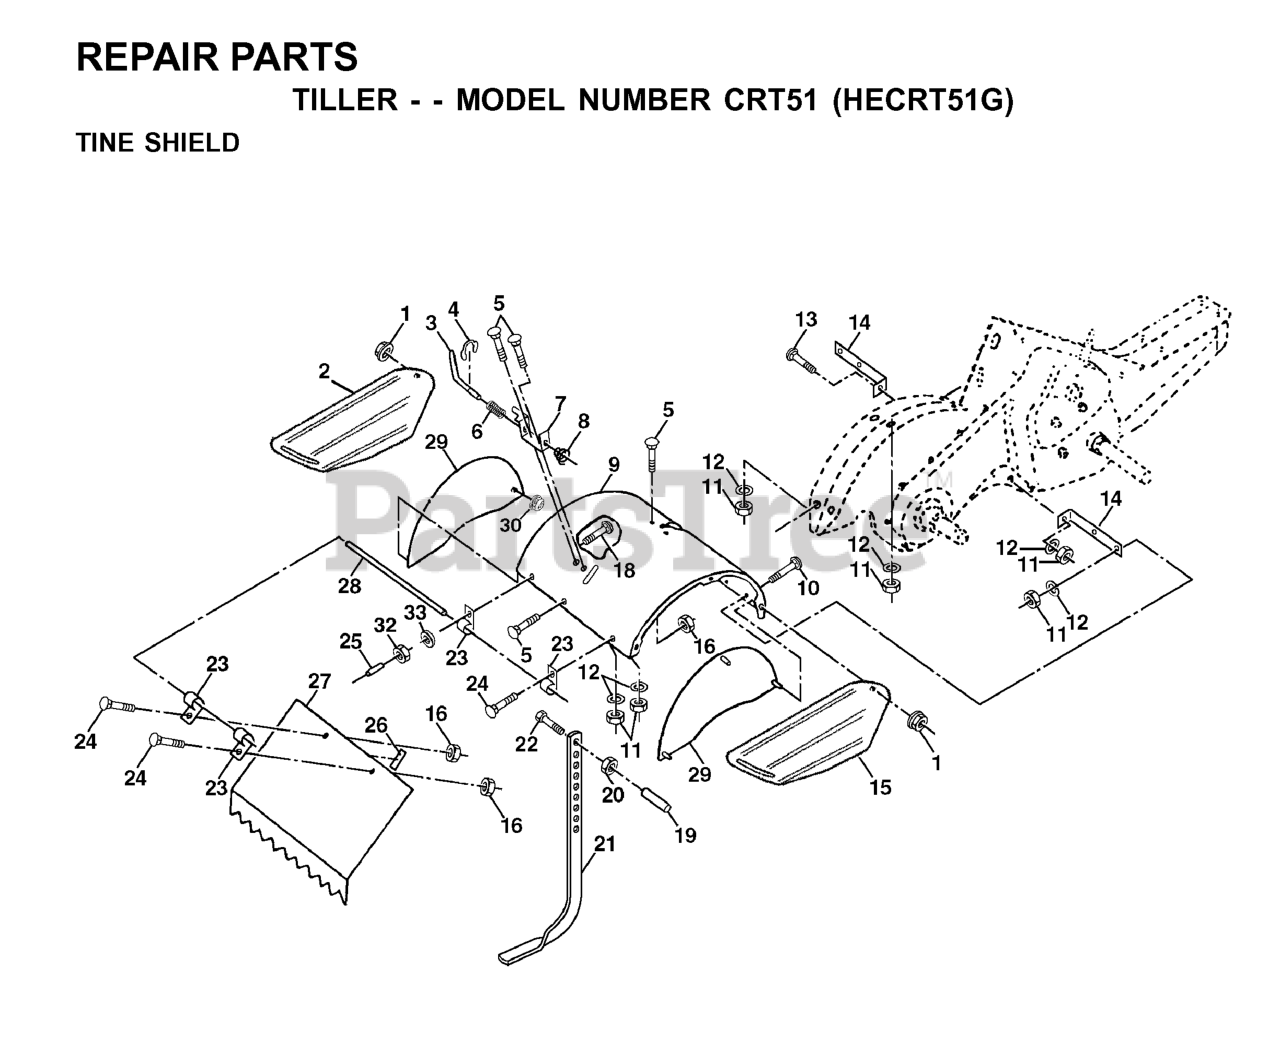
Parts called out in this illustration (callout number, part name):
1	NUT LOCK HEX FLANGE 5/16-18
2	SHIELD
3	STAKE PIN TI
4	KLIP RING TI
5	RP BOLT 5/16-18 X3/4 ZN/YEL GR
7	BRACKET.LATCH.STAKE.3.20.BLACK
8	SPRING CRT
9	SHIELD
12	WASHER.LOCK.HVY.HLCL.SPR.5/16
13	BOLT.CARRIAGE.5/16-18
14	BRACKET.TINE.SHIELD.TILLER.BLA
15	SIDE SHIELD RH
16	NUT T
20	NUT.HEX.3/8-16UNC
21	STAKE.DEPTH.16.CRT.BLACK
22	BOLT.375-16
25	VINYL CAP TI
26	PAD IDLER TI
27	SHIELD LEVELING
28	PIN.HINGE.TILLER
29	SIDE SHIELD
30	LOCKNUT-FLANGE 5/16-18
32	NUT
33	LOCKWASHER
